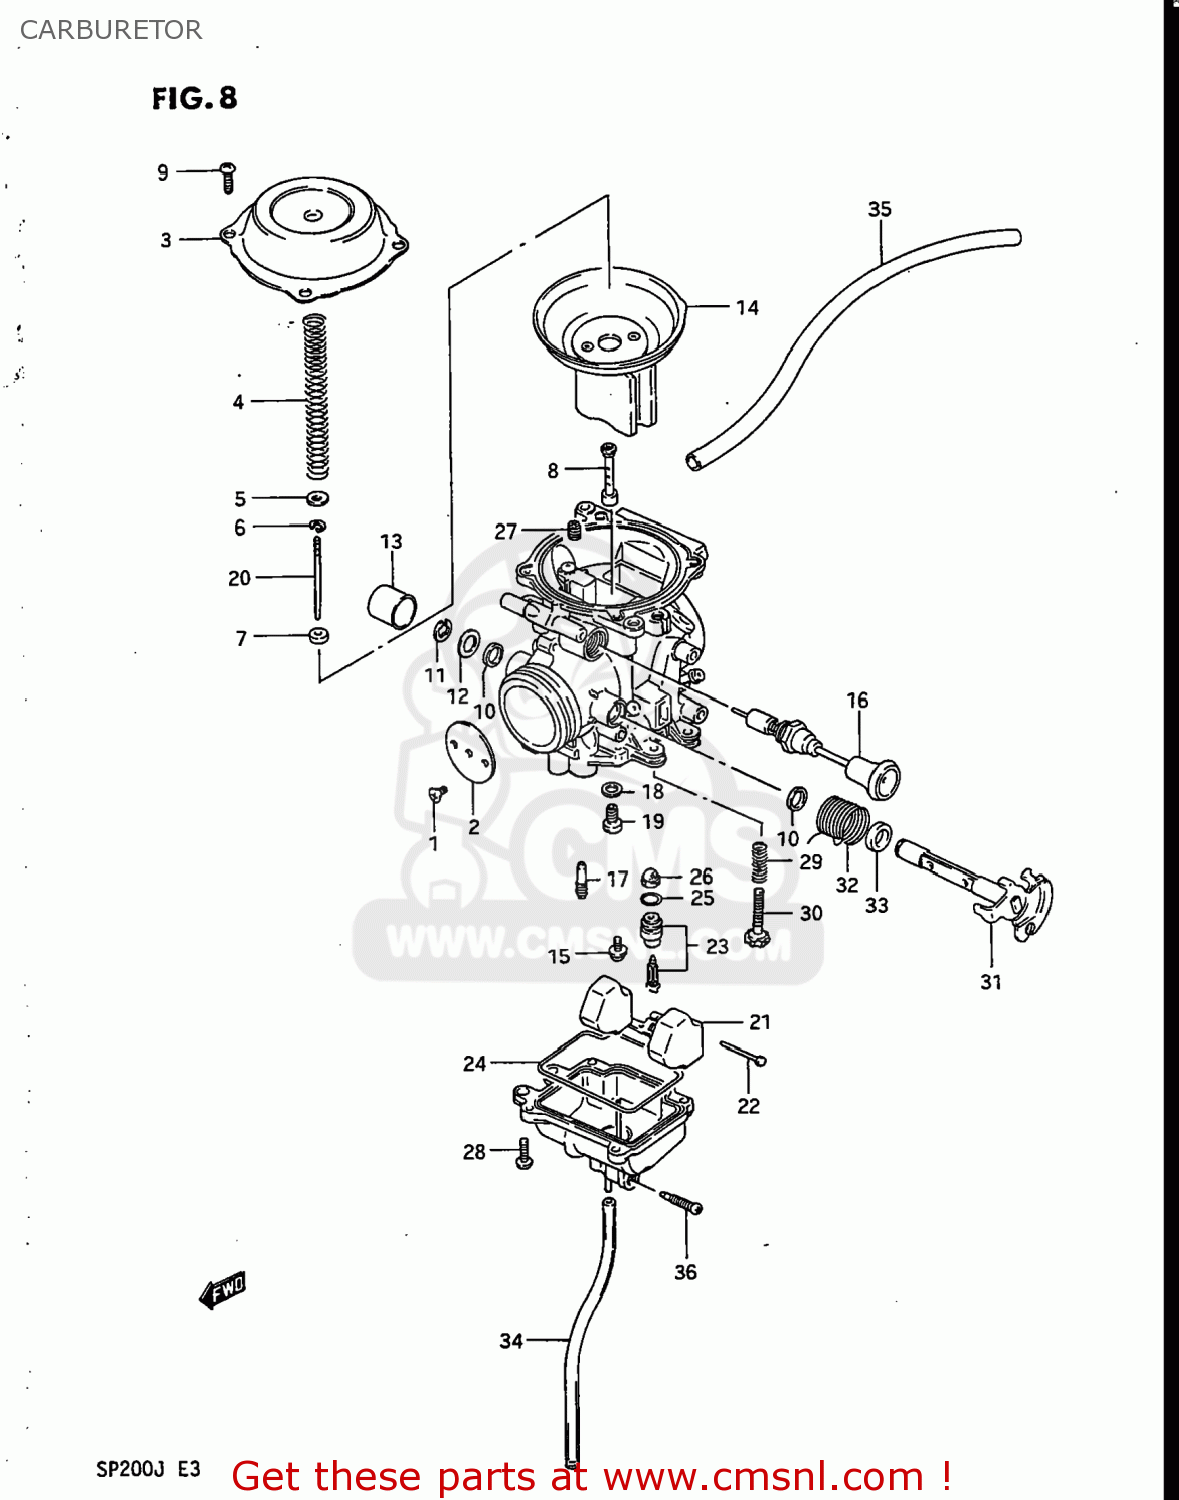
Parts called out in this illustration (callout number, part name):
1	SCREW
2	VALVE,THROTTLE
3	COVER,DIAPHRAGM
4	SPRING
5	RING
6	CAP,LEVER
7	RING
8	JET,NEEDLE(P-4)
9	SCREW
10	SEAL
11	E RING
12	GASKET,THROTTLE SHAFT (NAS)
13	CAP
14	DIAPHRAGM ASSY
15	SCREW
16	PLUNGER ASSEMBLY
17	JET(40)
18	WASHER,NEEDLE NOZZLE
19	JET,MAIN(122.5)
20	NEEDLE JET
21	FLOAT
22	PIN,FLOAT
23	VALVE ASSEMBLY,NEEDLE
24	O RING,FLOAT CHAMBER
25	O RING
26	FILTER
27	JET,AIR(150)
28	SCREW
29	SPRING,THROTTLE ADJUST
30	SCREW,THROTTLE STOP
31	SHAFT ASSEMBLY,THROTTLE
32	SPRING
33	RING
34	HOSE
35	HOSE
36	SCREW,DRAIN
